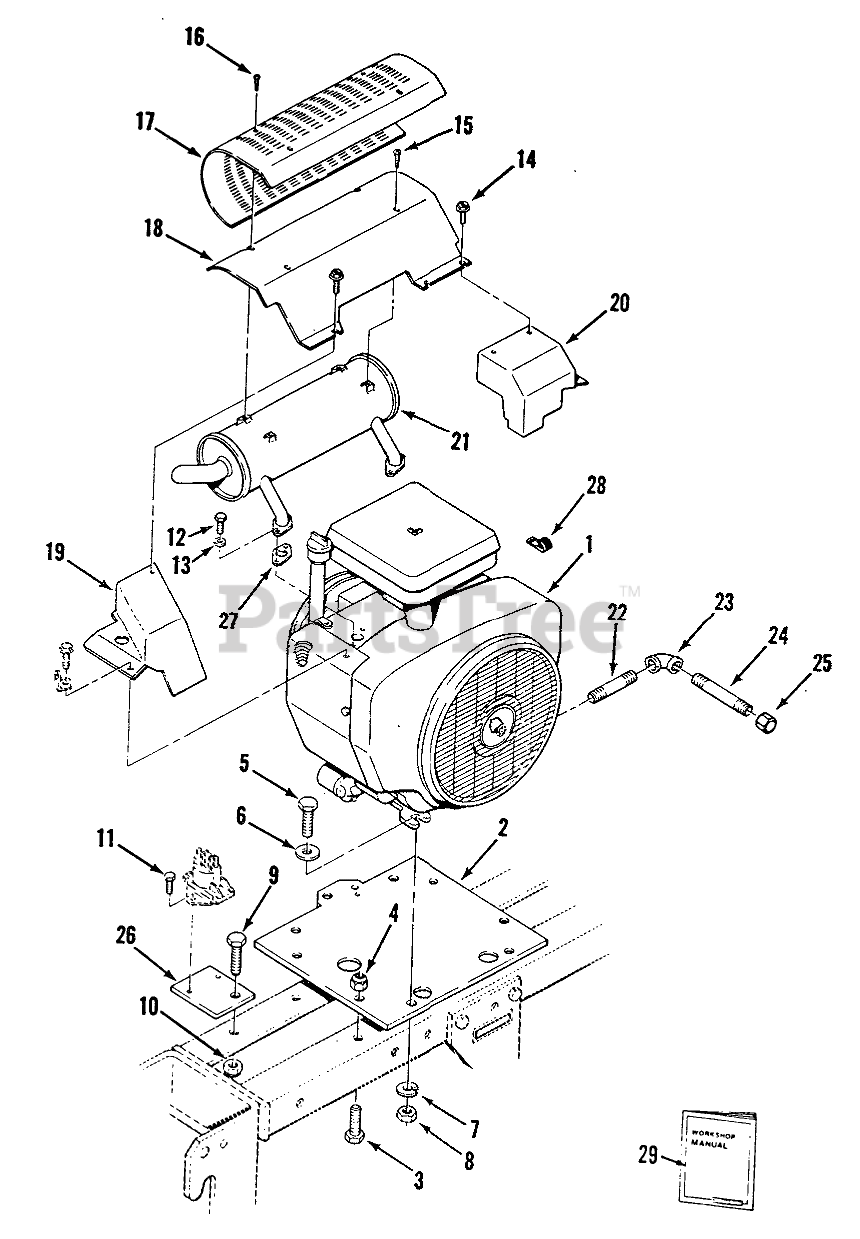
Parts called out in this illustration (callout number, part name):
2	Engine Plate
3	Bolt
4	NUT
5	BOLT
6	Washer
7	LOCKWASHER
8	Nut
9	BOLT
10	NUT
11	S.T. Bolt 1/4-20 x 1/2
12	Bolt
13	Lockwasher
14	Bolt
15	Screw
16	SCW 10-24 STAINLESS
17	X-REF 115783
18	Air Deflector
19	LH Exhaust Cover
20	RH Exhaust Cover
21	Muffler
22	Pipe
23	ELBOW 3/8 90 DEG
24	PIPE-NIPPLE 3/8 X 4"
25	Cap
26	PLATE-RELAY MOUNT B
27	Exhaust Gasket
28	CLIP
29	Onan Performer Twin Cylinder Service Manual
